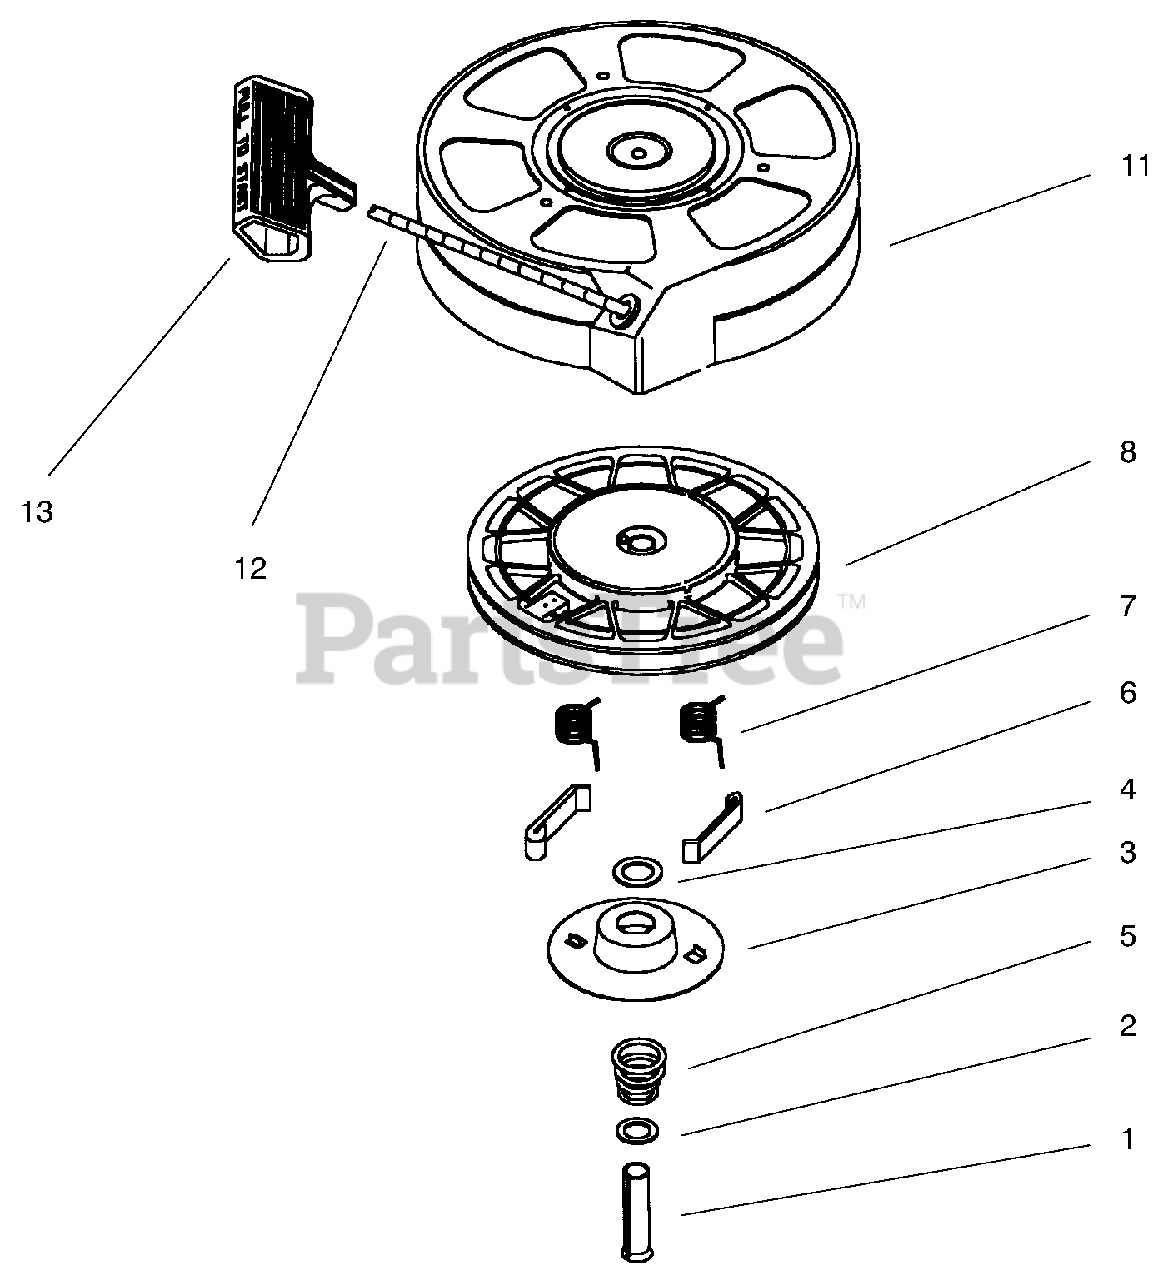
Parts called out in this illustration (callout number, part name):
3	Retainer
6	Starter Dog
7	Dog Spring
8	Pulley & Rewind Spring Ass'y
11	Starter Housing Ass'y (40 degree grommet)
12	Starter Rope (Length 98" x 9/64" dia.)
13	Starter Handle
